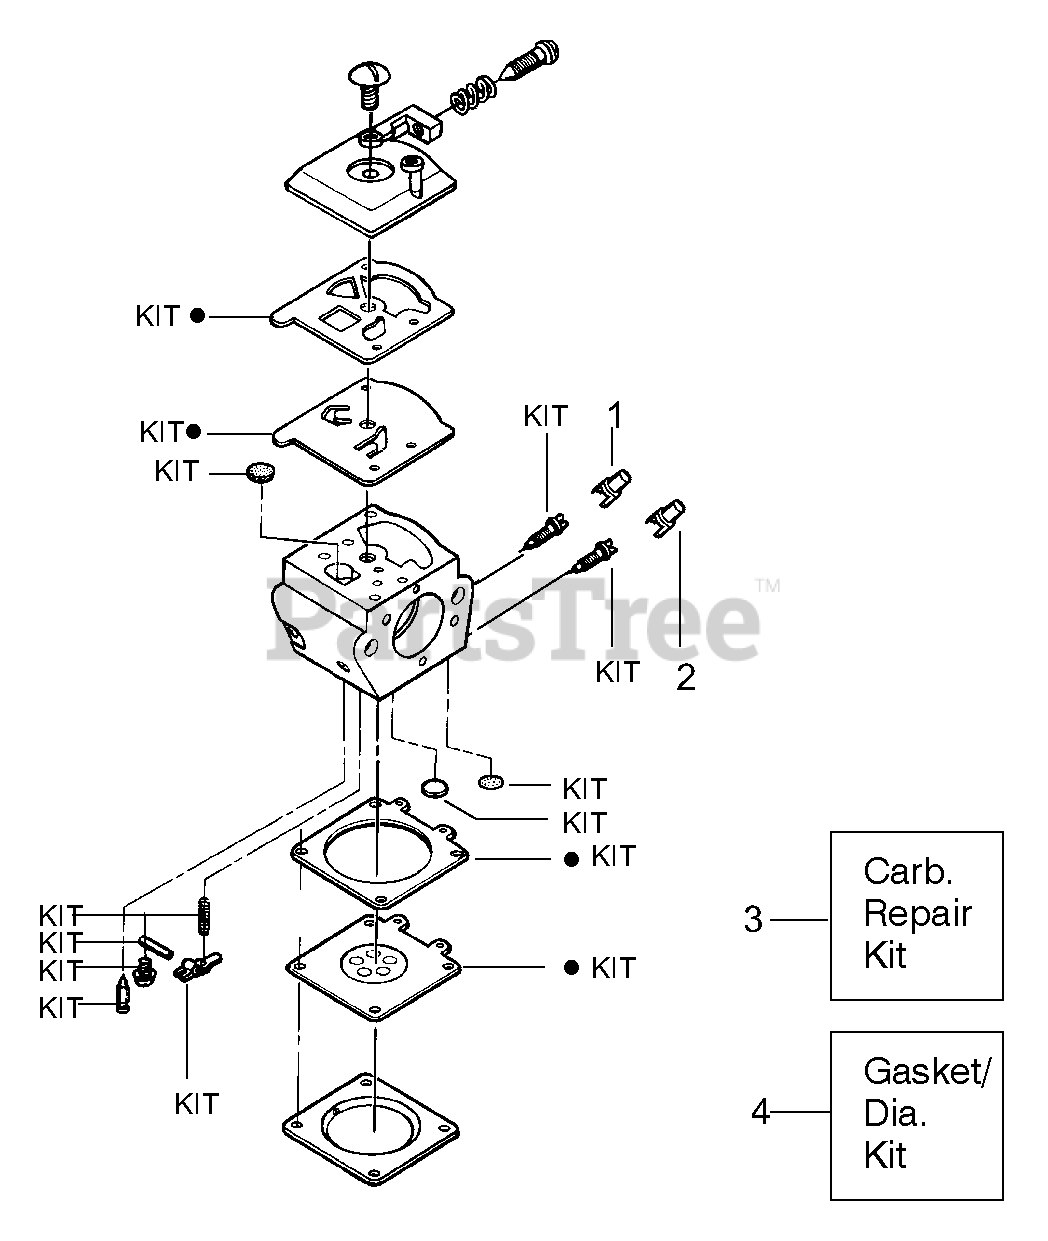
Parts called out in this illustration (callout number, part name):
1	Limiter Cap-High (brown)
2	Limiter Cap-Low (tan)
3	Carburetor Repair Kit Zama (C1Q-W8)
4	Gasket Diaphragm Kit Zama (C1Q-W8)
